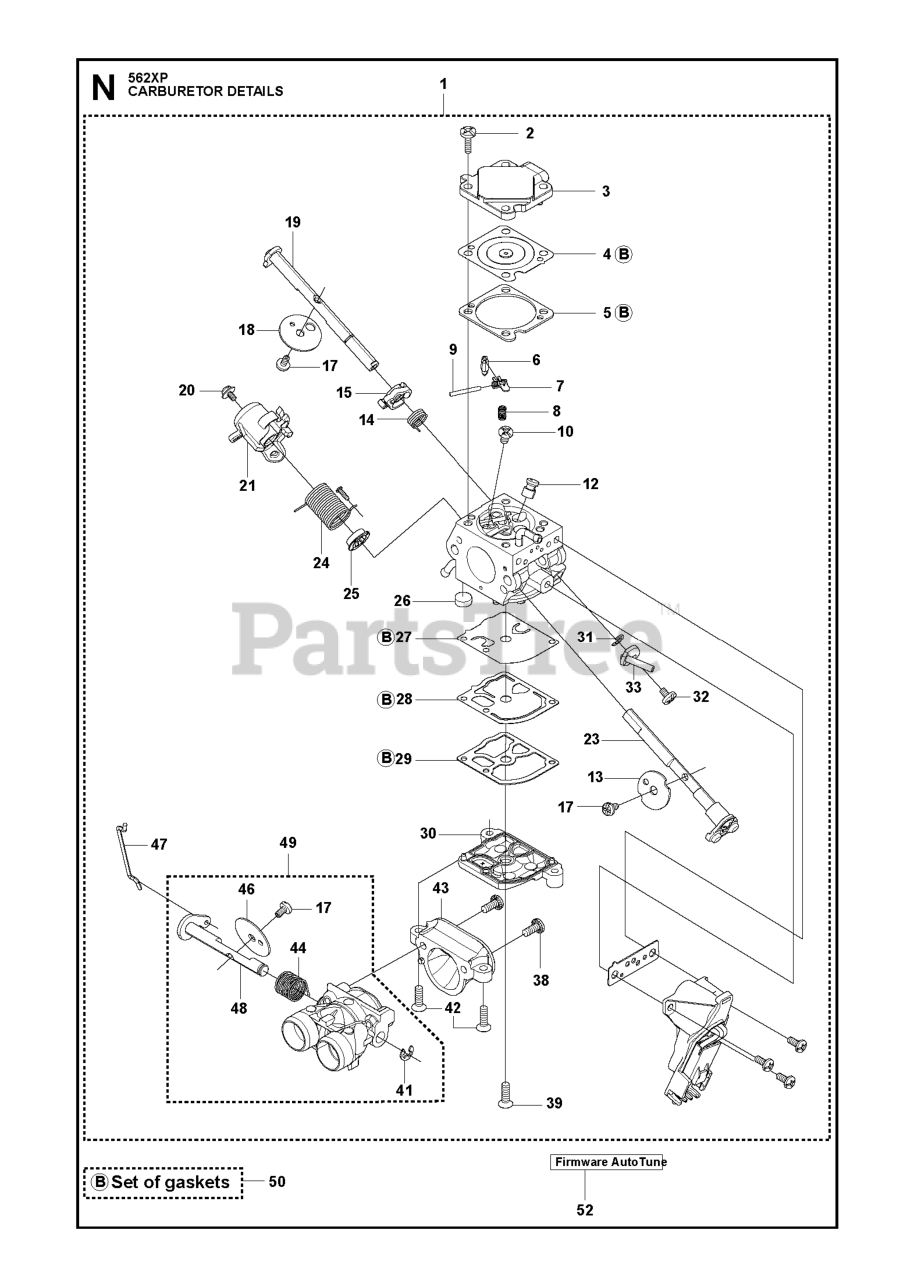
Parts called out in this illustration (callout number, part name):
1	CARBURETOR KIT 555 AUTOTUNE
1	CARBURETTOR KIT 60CC
6	INLET NEEDLE
9	PIN RETAINING SCREW
12	MAIN NOZZLE
13	VALVE
13	THROTTLE VALVE
18	CHOKE VALVE
19	SHAFT ASSY
21	THROTTLE LEVER
23	THROTTLE SHAFT
27	PUMP DIAPHRAGM
33	CHOKE LEVER
46	THROTTLE FLAP
48	SHAFT ASSY
49	THROTTLE VALVE ASSY
50	KIT GASKET AND DIAPHRAM
